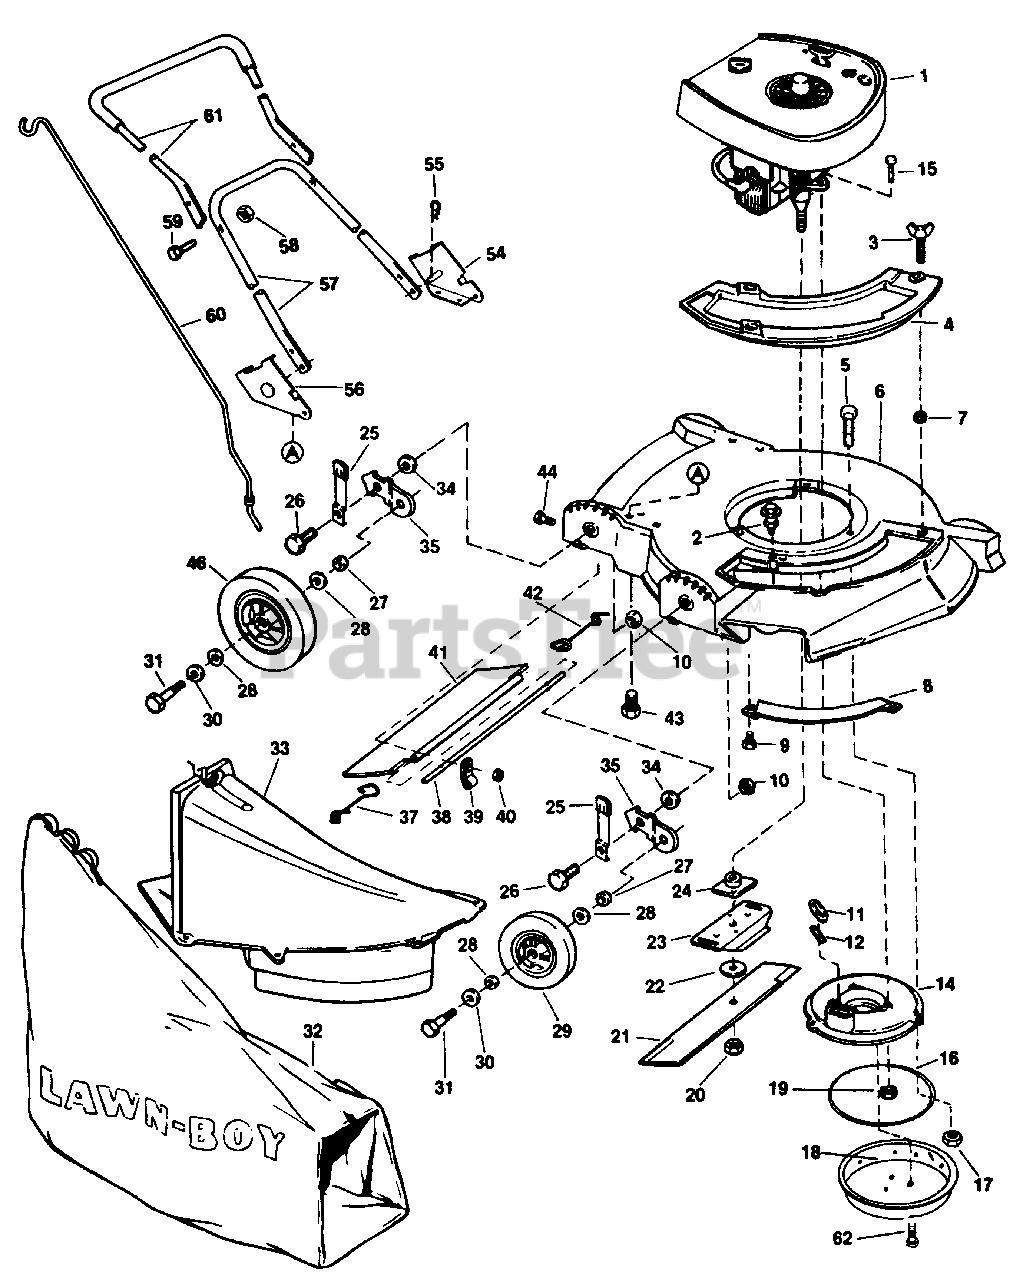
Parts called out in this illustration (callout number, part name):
1	See Page 32 for Engine, Magneto and Carburetor Parts List. See Note #2 at bottom of this page.
2	Screw
3	Wing Screw
4	Cover-Chute Opening
5	Screw-Muffler Plate to Housing
6	Housing Assembly 19" Only
6	Housing Assembly 21" Only
7	Grommet
8	Toe Bar
9	Screw
11	Sleeve-Muffler Gasket
12	Gasket-Exhaust
14	Muffler Plate Assembly
16	Gasket-Muffler
17	Nut-Nylok
18	Muffler
19	Nut-Muffler
20	Nut-Blade
21	Blade-21" Only
21	Blade-19" Only
22	Washer-21" Only
23	Stiffener-Blade
24	Collar & Plate Assembly
25	Knob & Spring Ay.
26	Bolt-Wheel Brkt. to Knob & Spring Ay.
28	Felt Washer
29	Wheel & Tire Assembly-6"
30	Washer-Wheel Bolt Head
31	Bolt-Shoulder, Wheel
33	Chute Assembly
34	Washer-Whl. Brkt. Mtg.
35	Wheel Hgt. Adj. Brkt.
37	Spring-R.H.
38	Rod
41	Shield
42	Spring-L.H.
43	Screw-Handle Bracket
46	Wheel & Tire Assembly-8"
54	Bracket-Handle, Left
55	Hairpin
56	Bracket-Handle, Right
57	Handle-Bottom
58	Nut-Handle
59	Screw-Handle
60	Bag Rod
61	Handle and Grip Assembly-Top
62	Bolt, Muffler
